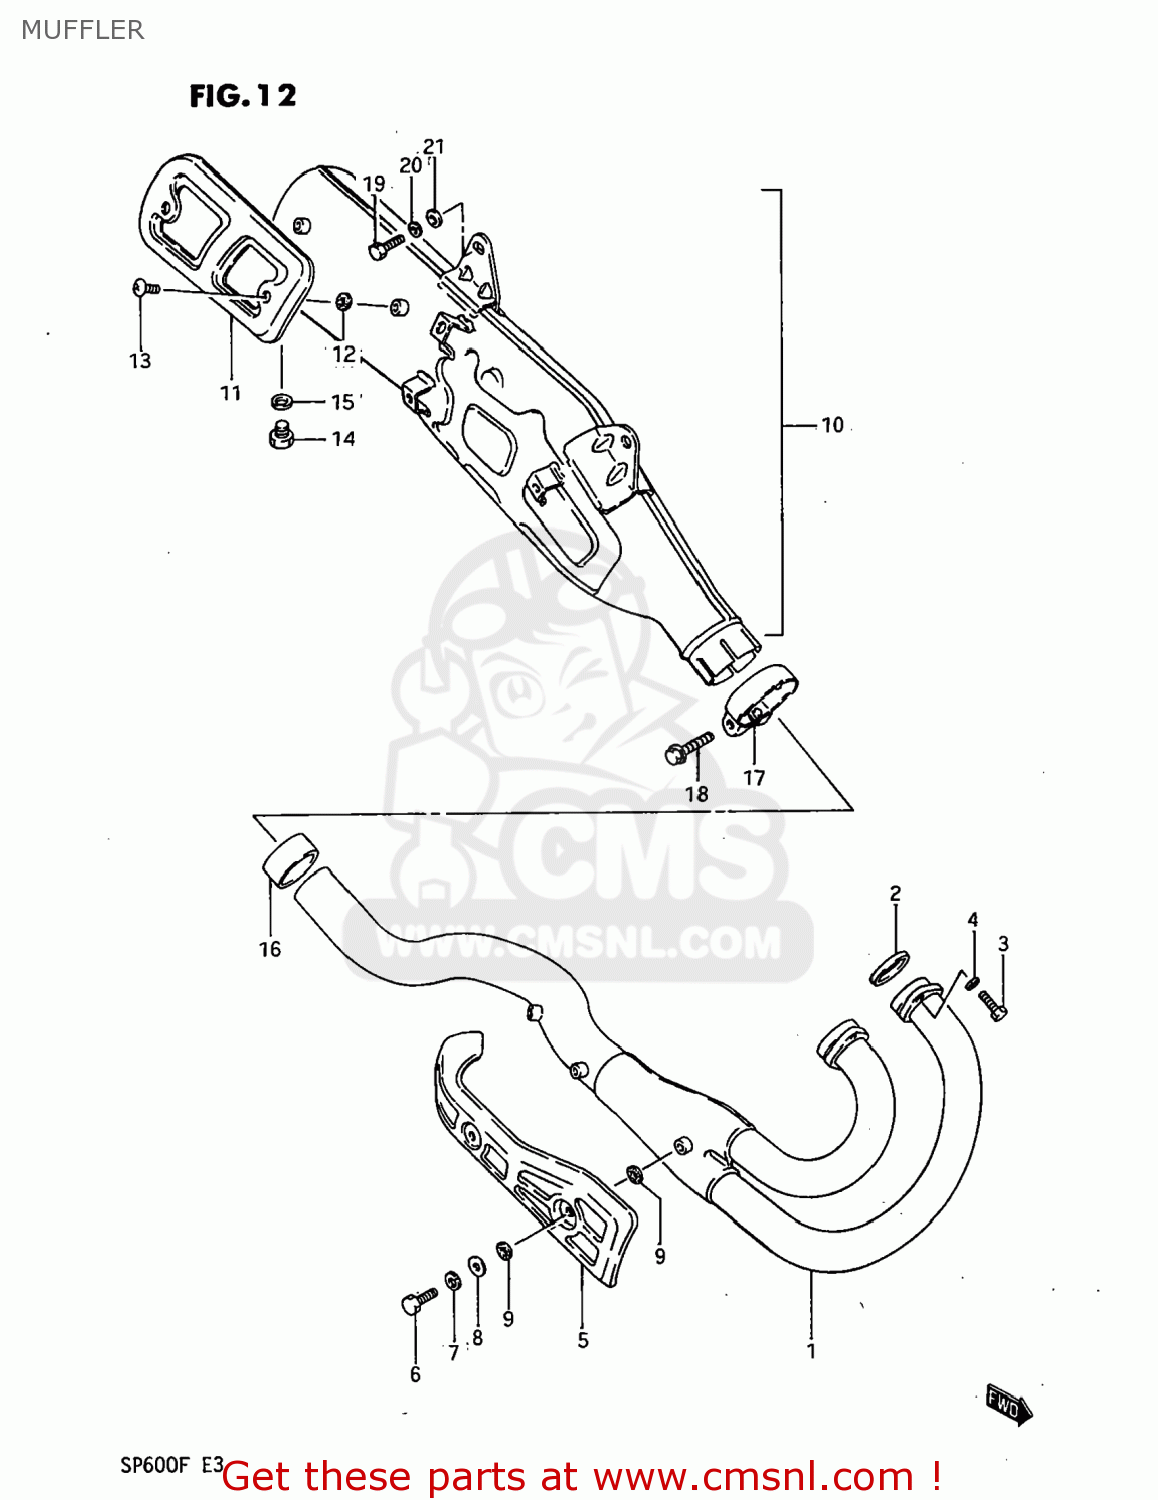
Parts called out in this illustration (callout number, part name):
1	PIPE,EXHAUST
2	GASKET,EXHAUST PIPE
3	BOLT
4	WASHER,LOCK
5	COVER,EXHAUST PIPE
6	BOLT
7	WASHER,LOCK
8	WASHER
9	GASKET
10	MUFFLER ASSEMBLY
11	COVER,MUFFLER
12	GASKET,EXHAUST PIPE (MCA)
13	SCREW
14	PLUG,12X9
15	GASKET(12.1X16.2X3.7) (NAS)
16	CONNECTOR,MUFFLER
17	CLAMP,MUFFLER CONNECTOR
18	BOLT
19	BOLT
20	LOCK WASHER
21	WASHER
